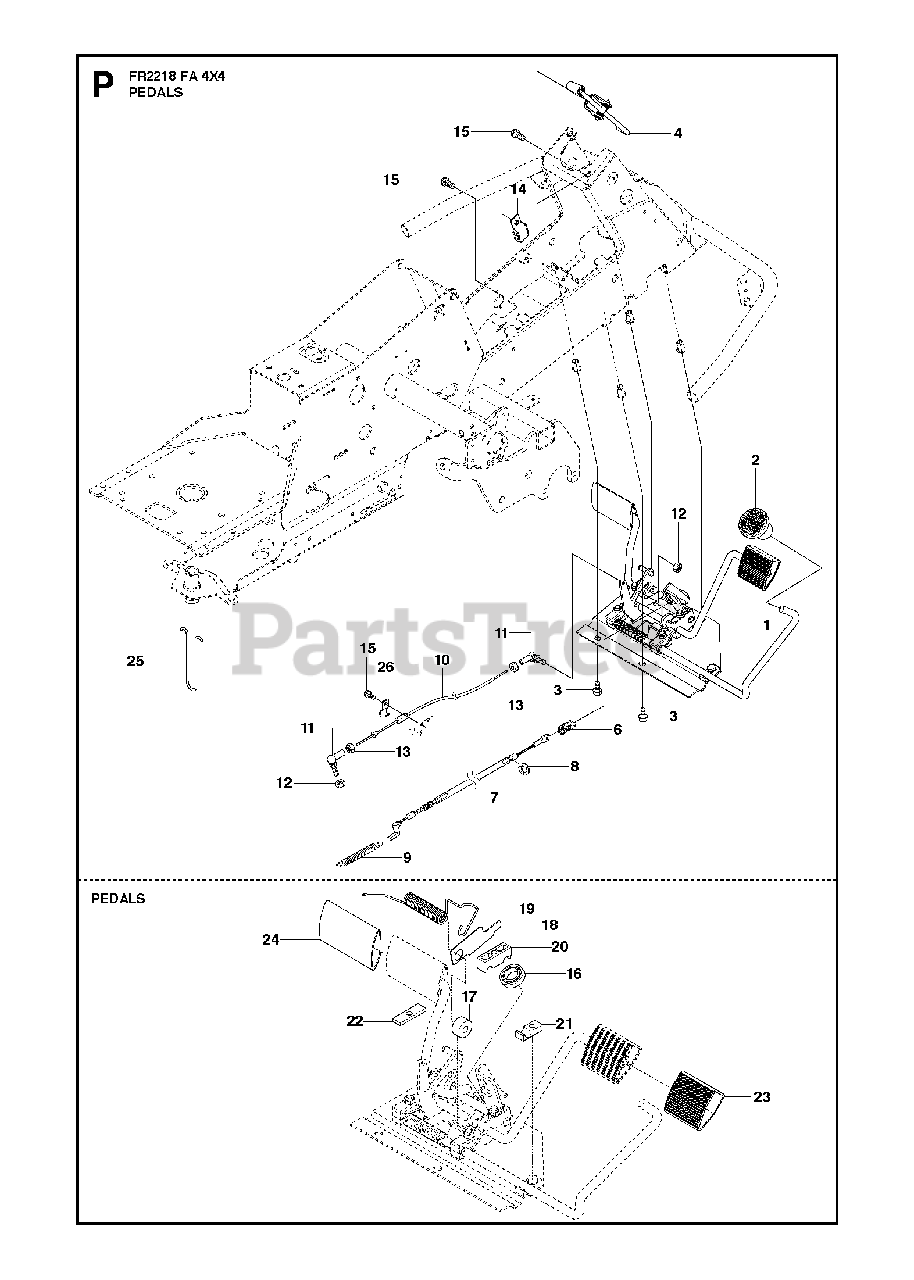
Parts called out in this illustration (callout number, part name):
1	PEDAL ASSEMBLY
2	KNOB
4	BRAKE LEVER ASSY
7	BRAKE WIRE
9	CONTROL CABLE
10	CONTROL CABLE
11	CONNECTOR
12	LOCKNUT M5
16	BALL BEARING 6002-2RS1
17	ROLLER
18	PLATE
19	SPRING
20	PEDAL SHAFT CLAMP
21	SUPPORT
22	PLATE
23	PEDAL RUBBER
24	PEDAL RUBBER, SF
25	CABLE HOLDER
